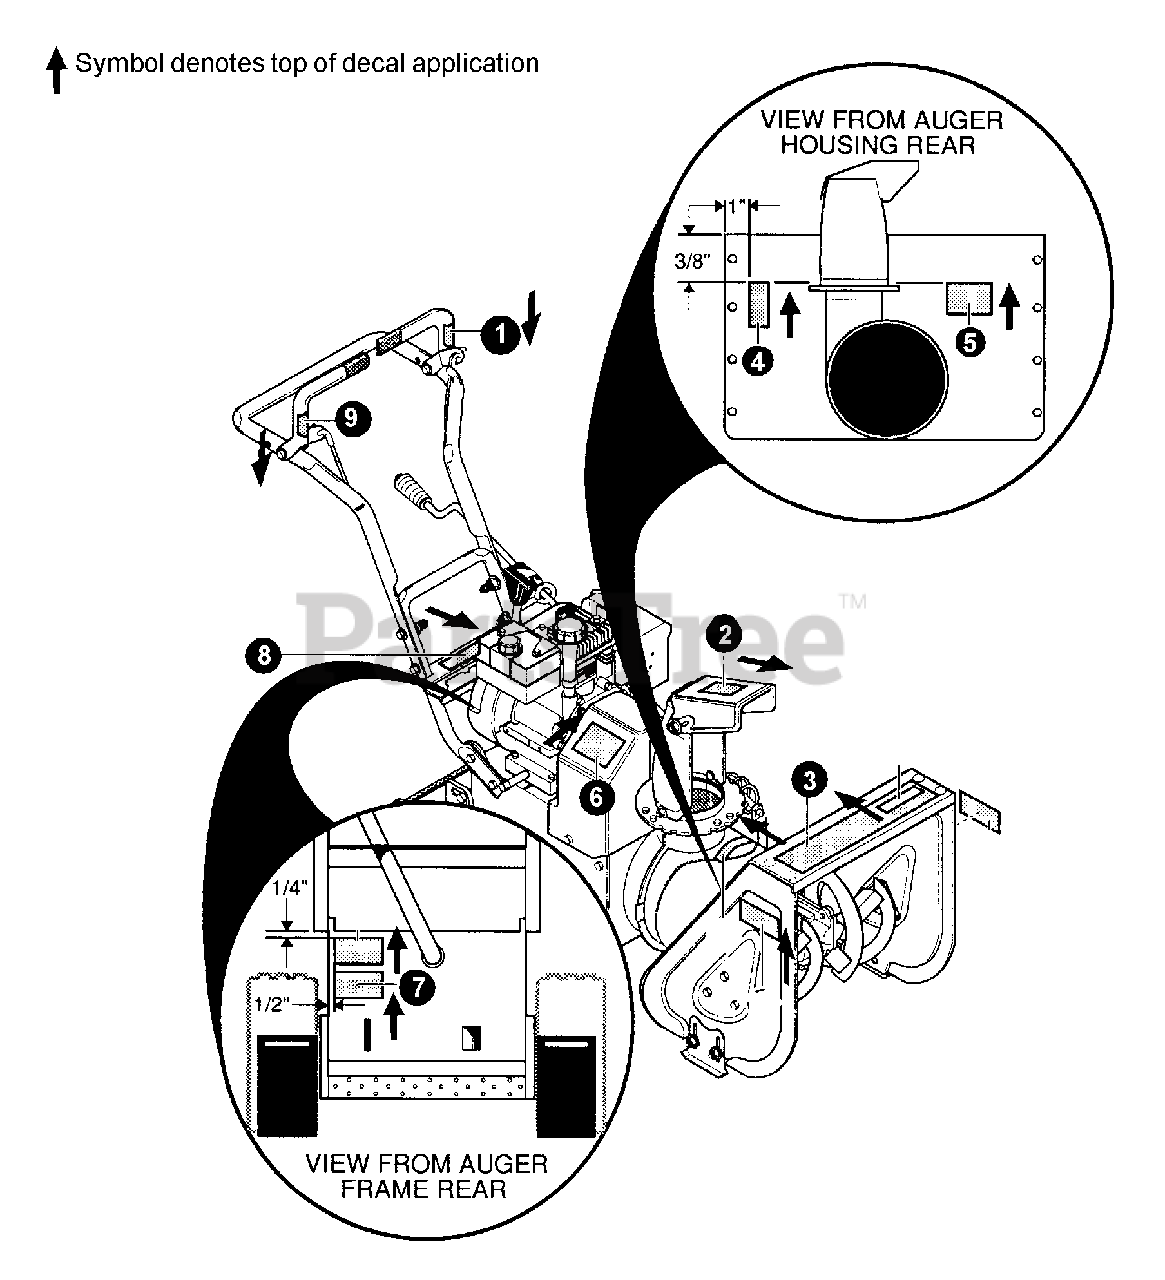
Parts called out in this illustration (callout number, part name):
1	LABEL - TRACTION DRIVE ENGAGE
2	LABEL - DANGER
3	LABEL - ECHO
4	LABEL - DANGER
5	LABEL - DANGER
6	LABEL - BELT STRETCH & ADJ
7	LABEL - ADJ OF DISC
8	LABEL - GEAR SELECTOR
9	LABEL - AUGER DRIVE ENGAGE
